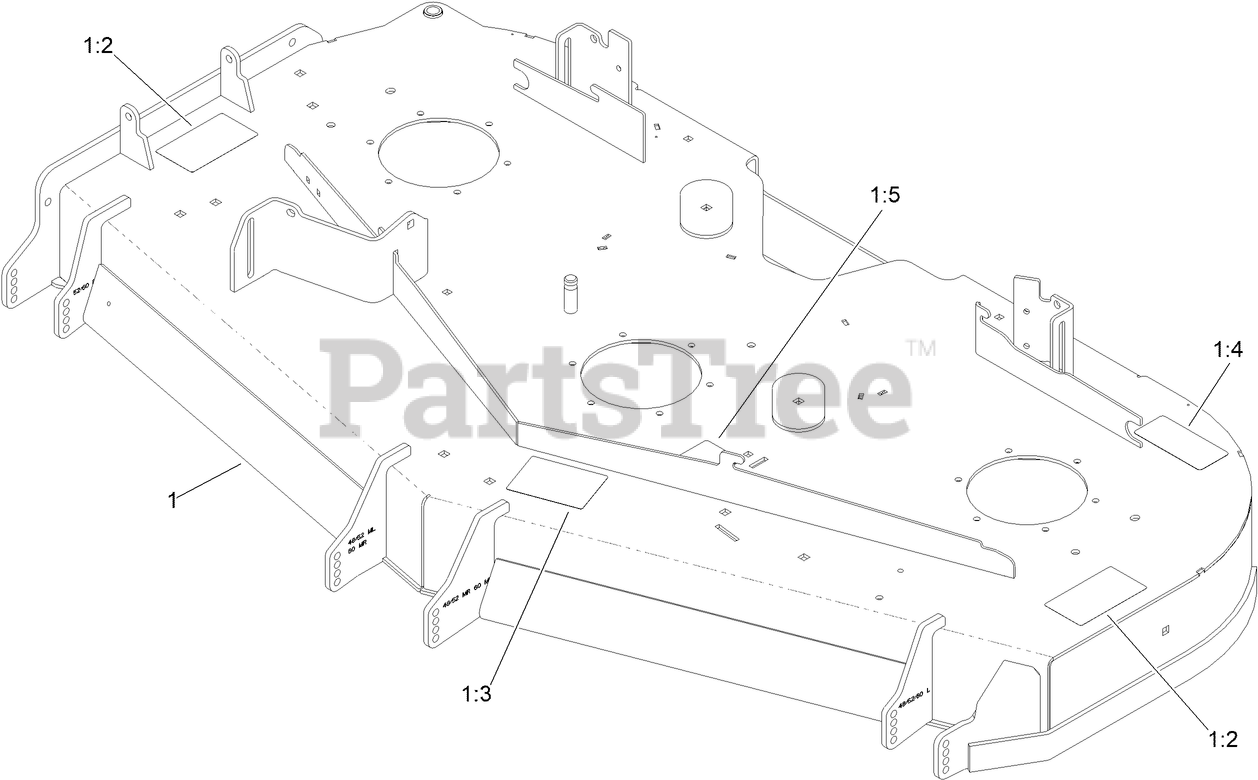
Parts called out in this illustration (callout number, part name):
1	ASM-DECK W/DECALS
1:2	DECAL-DANGER
1:3	DECAL-SCALP, ANTI
1:4	DECAL-TORQUE, BLADE BOLT
1:5	DECAL-ROUTING, BELT
